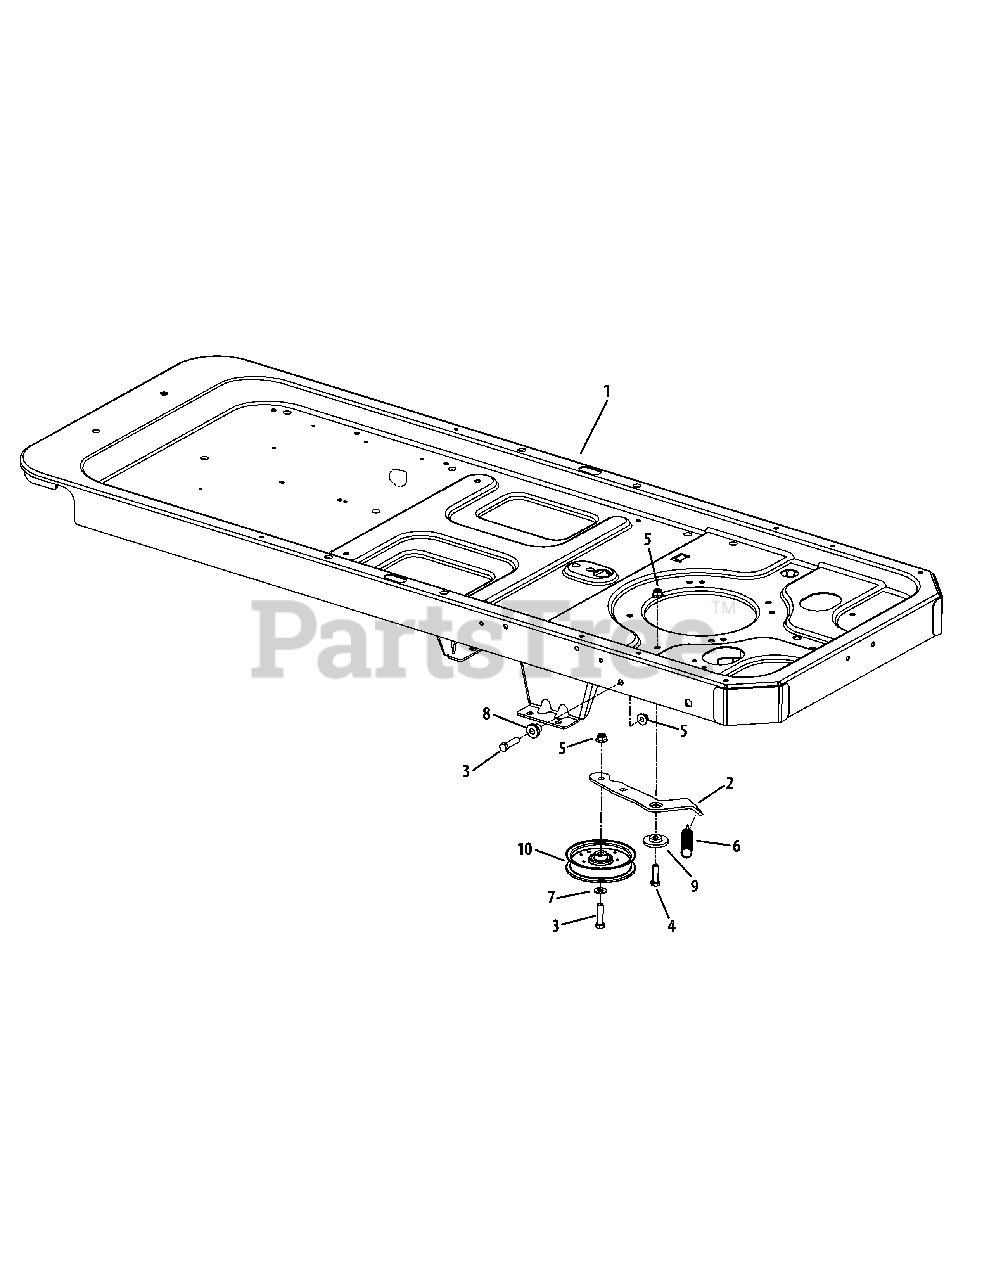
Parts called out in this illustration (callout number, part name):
2	Drive Idler Arm
3	Hex Screw, 3/8-16 x 1.5
4	Hex Screw, 3/8-16 x 1.25
5	Flange Nut, 3/8-16
6	Extension Spring, .75 x 5.06
7	Flat Washer, .406 x .875 x .059
8	Shoulder Spacer, .39 x 1.0 x .7
9	Shoulder Spacer, .884 x .19
10	Idler Pulley, 4.25 Dia.
